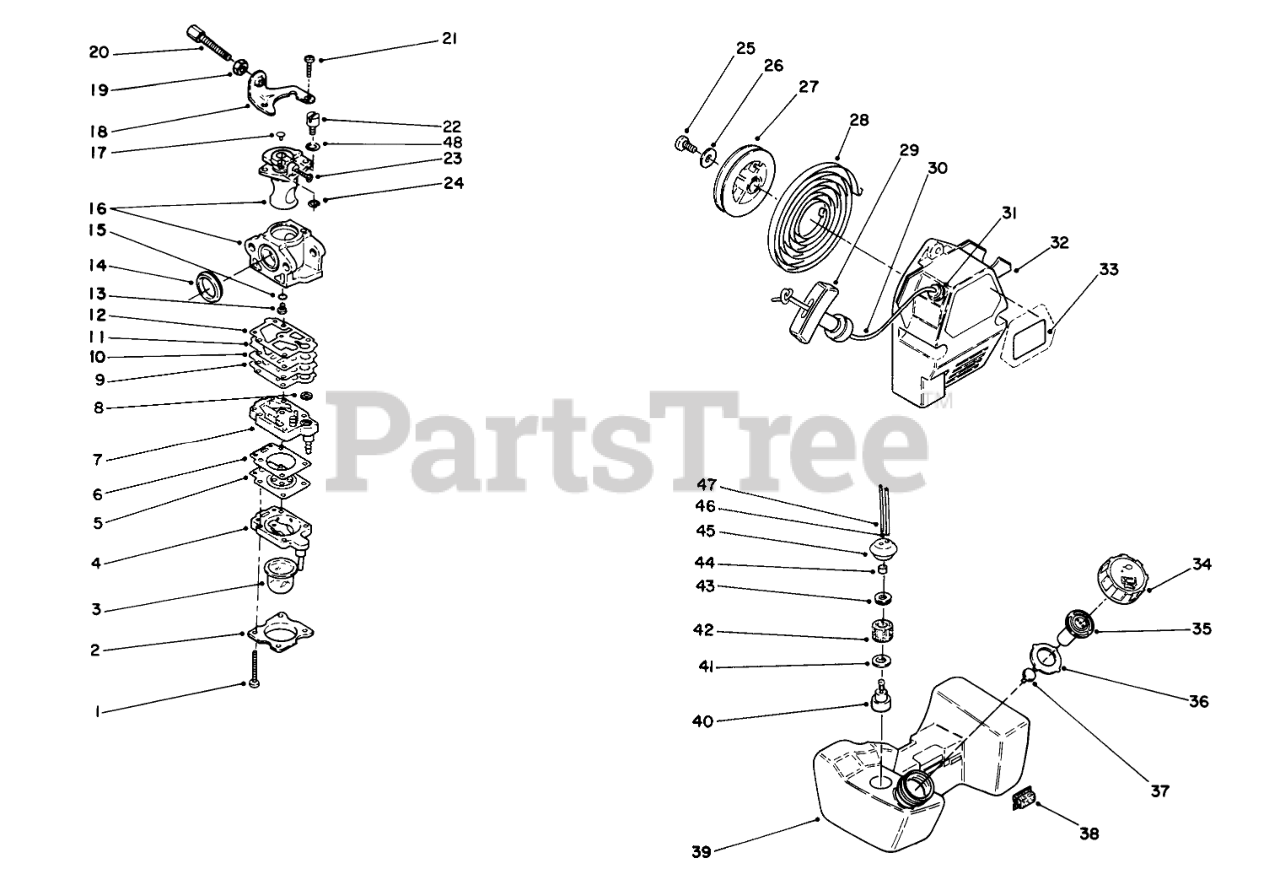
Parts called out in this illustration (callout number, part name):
1	SCREW
2	Cover-Primer
3	PRIMER PUMP
4	PRIMER BODY
5	DIAPHRAGM
6	DIAPHRAGM GASKET
7	Body Assembly (Incl. Ref. #8)
8	SCREEN
9	PUMP GASKET
10	Plate
11	DIAPHRAGM
12	DIAPHRAM GASKET
13	MAIN JET
14	RUBBER CARB GASKET
15	MAIN JET O-RING
16	Body-Carburetor (Ref.)
18	BRACKET
19	LOCKNUT
20	ADJUSTING SCREW
21	SCREW
22	Holder-Wire
23	THROTTLE VALVE
25	SCREW
26	WASHER
28	SPRING
29	Knob-Starter
30	Rope-Recoil
31	GUIDE
32	RECOIL CASE
33	Decal-Toro
34	FUEL TANK CAP
35	BREATHER VALVE
36	PACKING
39	Tank Assembly-Fuel (Incl. Ref. #34-37 & 40-47)
40	Weight-Filter
42	Filter-Fuel
43	Washer-Seal
44	COLLAR
45	FUEL TANK GROMMET
46	TUBE, FUEL
47	RETURN FUEL HOSE
48	WASHER
